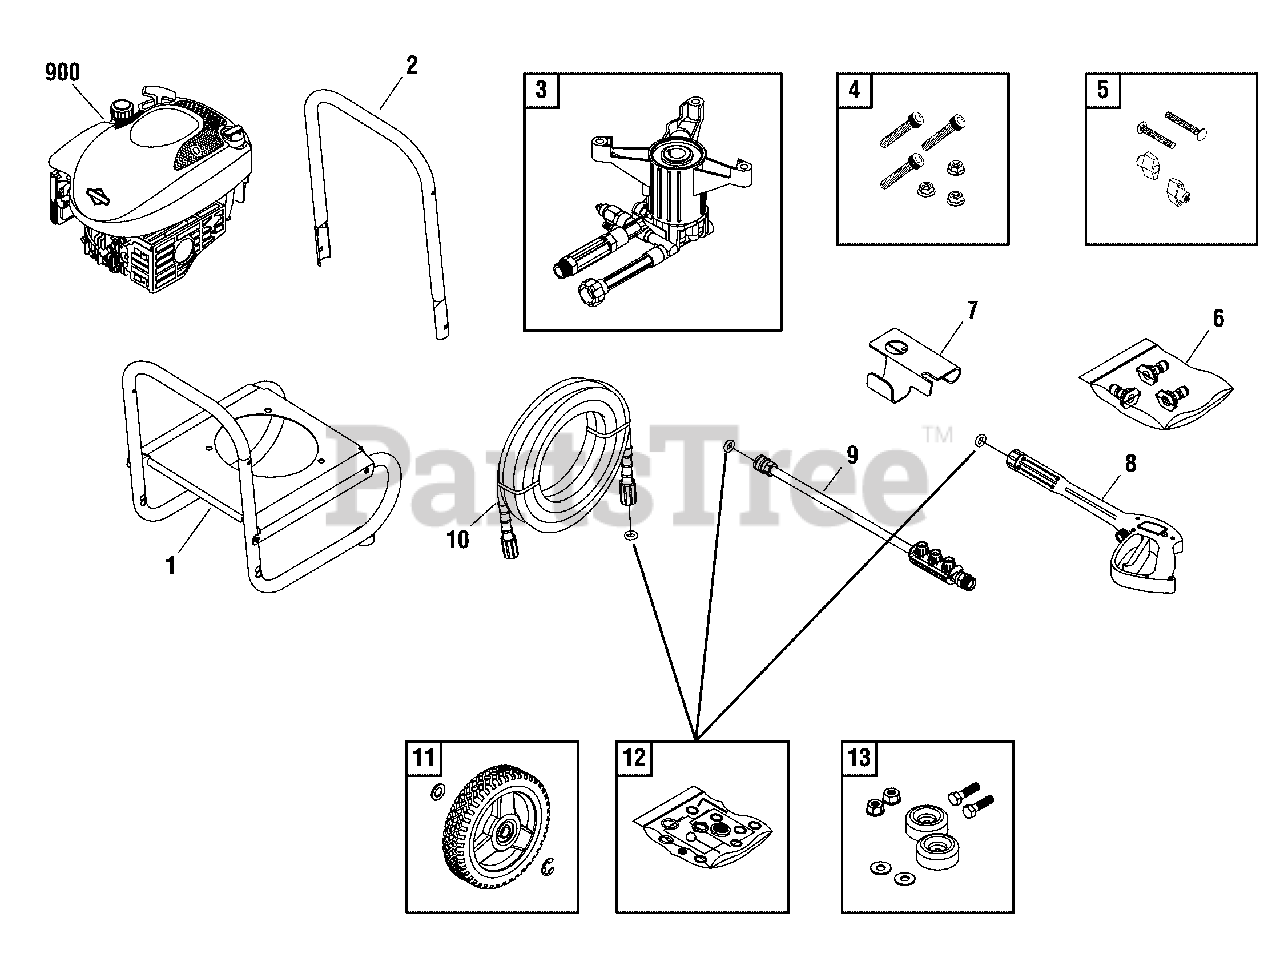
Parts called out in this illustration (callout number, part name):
3	PUMP
4	KIT-HARDWARE PUMP MOUNTING
5	KIT-HARDWARE HANDLE
8	GUN
10	HOSE
12	KIT-0-RING
13	KIT-VIBRATION MOUNT
900	** ENGINE
